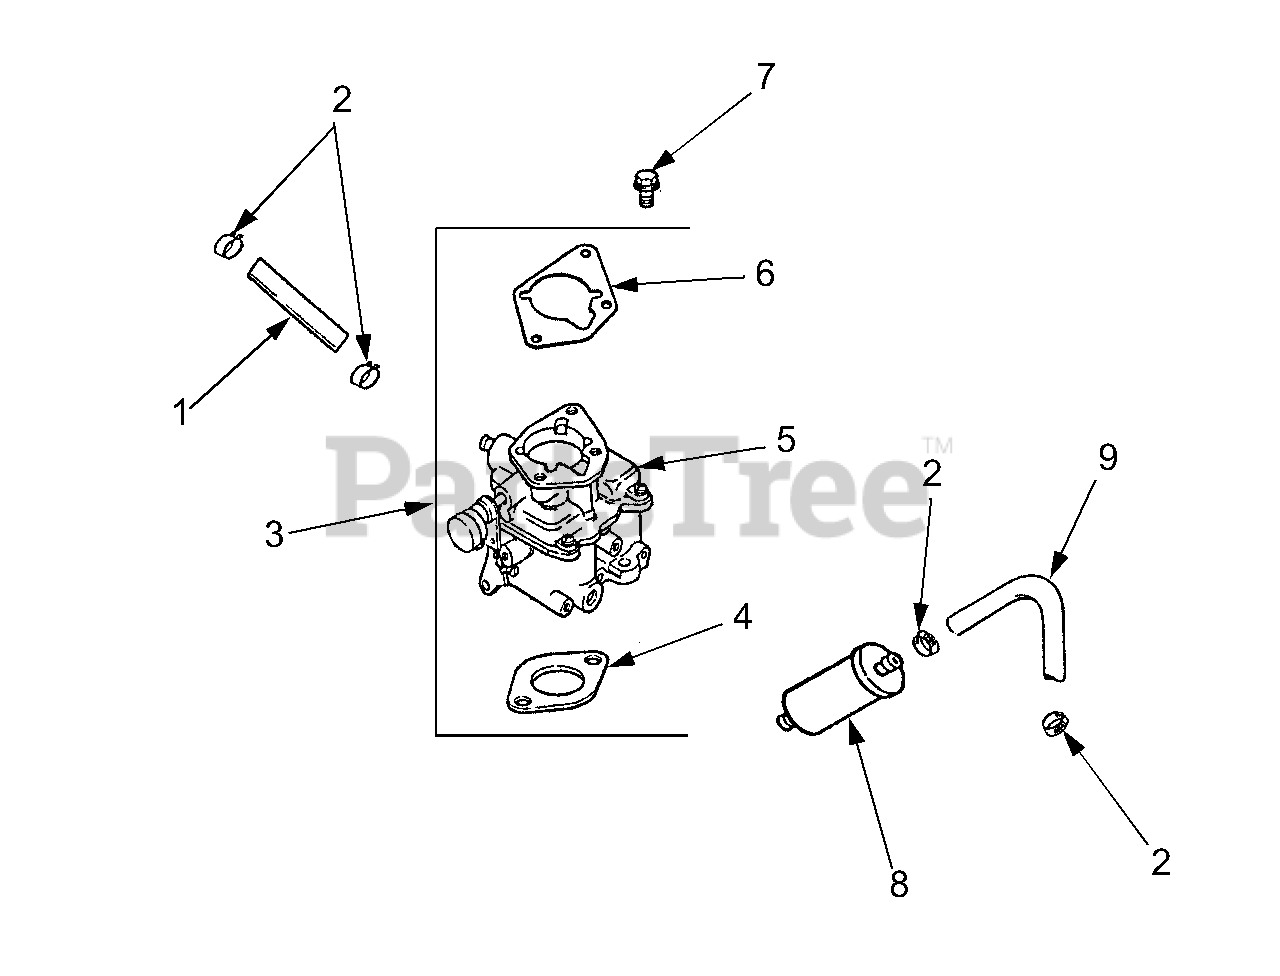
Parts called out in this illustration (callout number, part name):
1	Line, Fuel 10"
2	Clamp, Hose
3	Kit, Carburetor w/Gasket
4	Gasket, Carburetor
5	Carburetor Assembly
6	Gasket, Air Cleaner Base
7	Screw, Hex Flange
8	Filter, Fuel
9	Line, Fuel 11"
